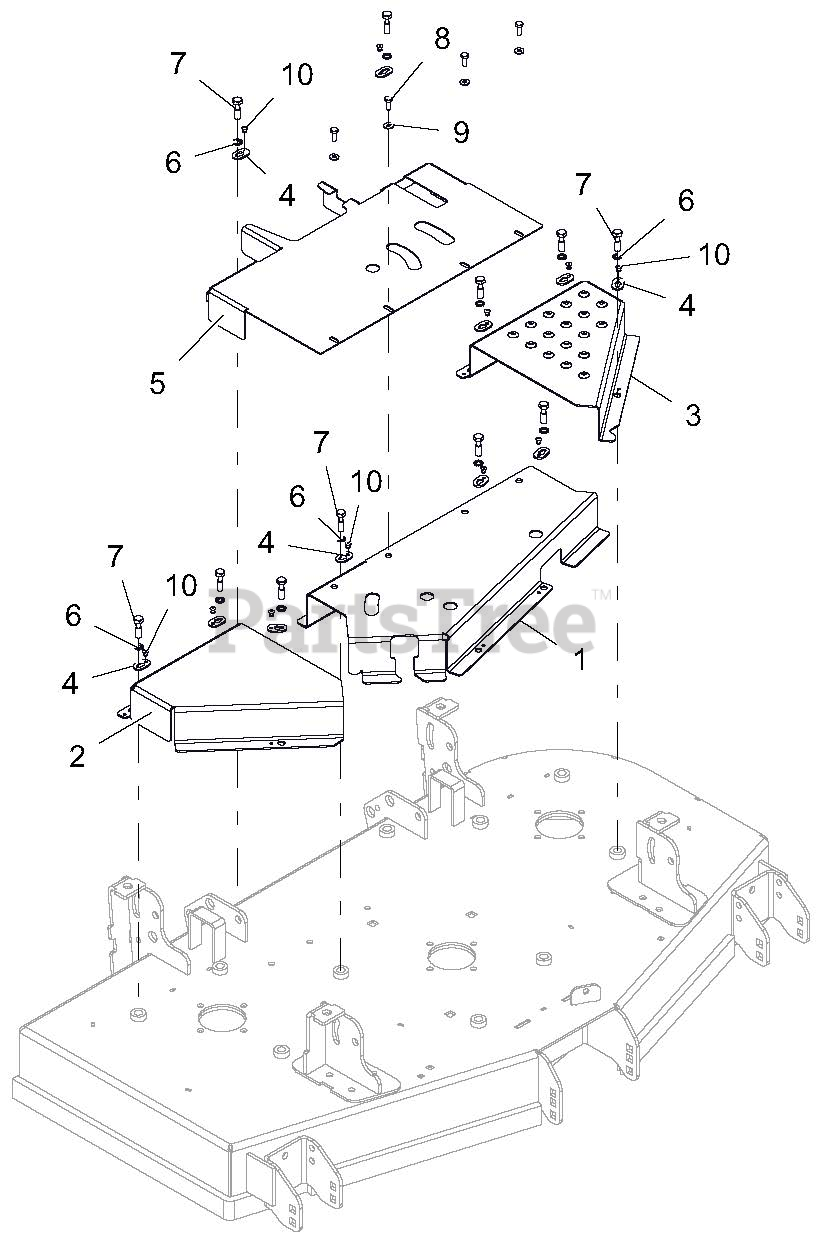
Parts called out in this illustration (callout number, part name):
1	WLDMT, FRONT BELT SHIELD
2	GUARD, RH PT200 CE BELT
3	GUARD, LH PT200 CE BELT
4	KEEPER, BOLT
5	SHIELD, BELT REAR
6	LOCK, WSHR-EXT 0.391 X 0.628 X 0.036 YWZC
7	BLT, HEX 0.38-16 X 1.25 GR5 CAPTIVE
8	BLT,HEX .50-13X3.00 GR5 FTH YZ
9	WSHR-FL-STL.281X.62X.065 YWZC
10	RVT-POP .187x.250 (#64) YWZC
